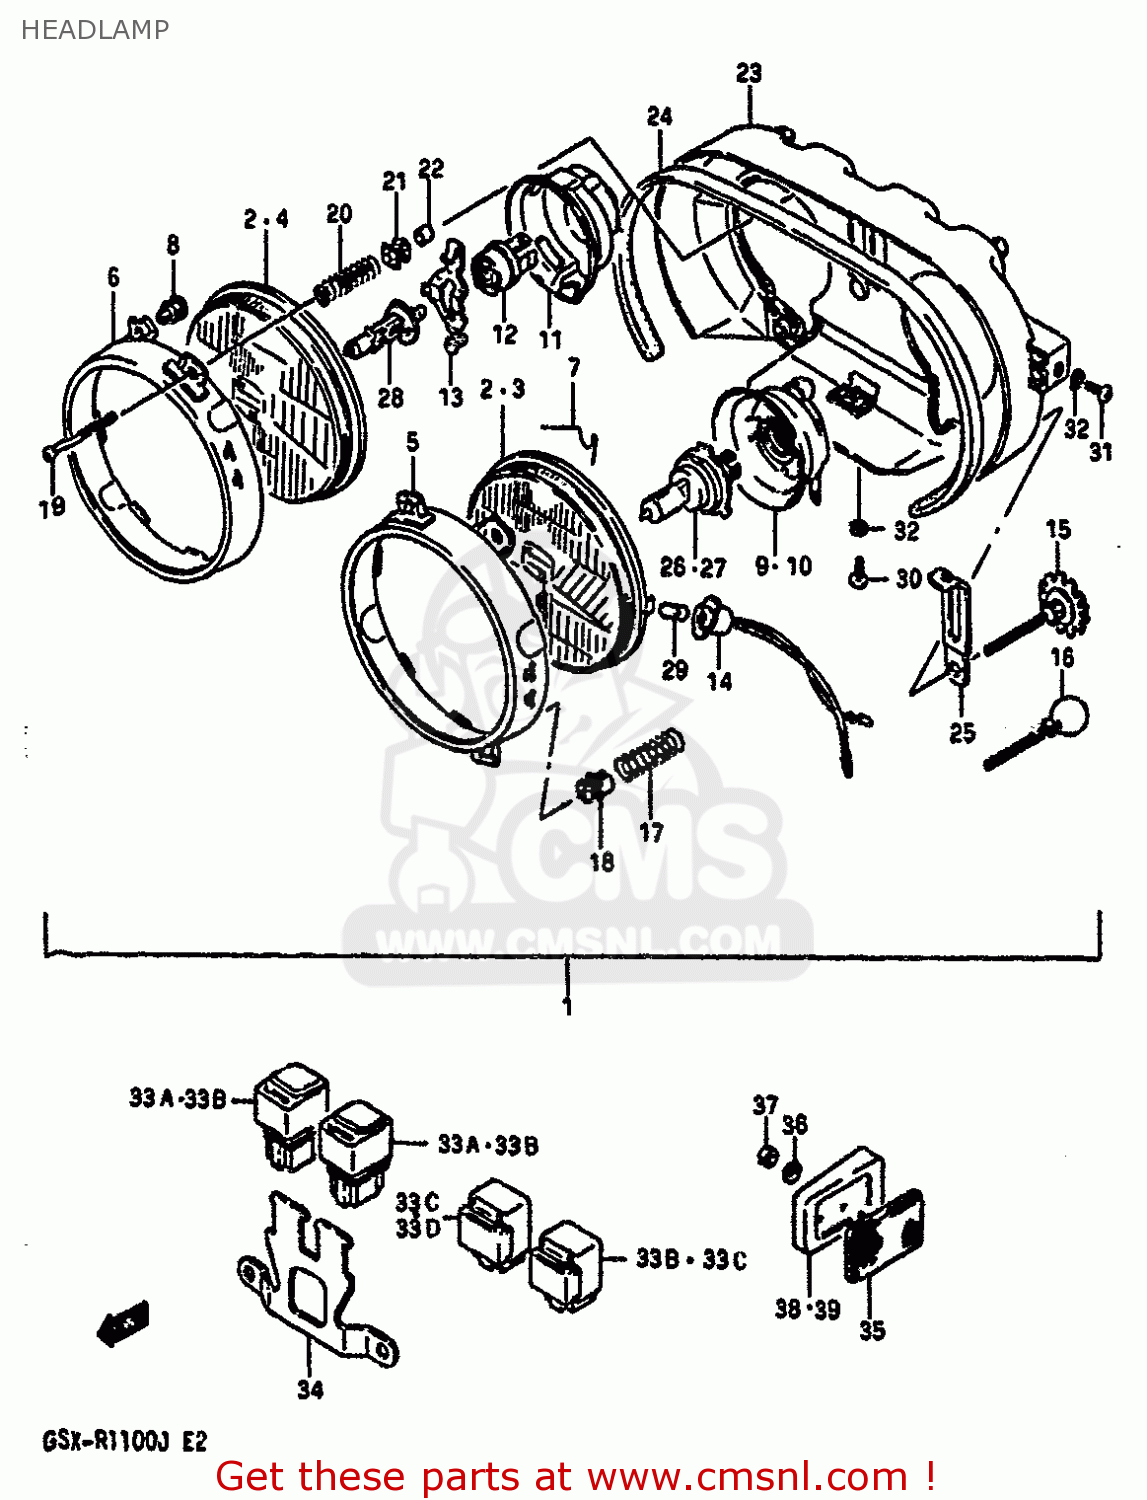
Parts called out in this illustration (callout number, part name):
1	HEADLAMP ASSY
2	UNIT
3	LAMP UNIT,L
4	UNIT,RH
5	RING,RETAINING,LEFT
6	RING,RETAINING,RIGHT
7	SPRING
8	SCREW,SPHERICAL
9	COVER,SOCKET
10	COVER,SOCKET
11	COVER, SOCKET,LH
12	ADAPTER
13	SPRING,PLATE
14	SOCKET
15	SCREW,ADJUSTER
16	SCREW,ADJUSTER
17	SPRING
18	NUT
19	SCREW,ADJUSTER
20	SPRING
21	NUT
22	CAP,SCREW
23	HOUSING,HEADLAMP
24	GASKET (NAS)
25	CLAMP
26	BULB(12V60/55W,H4)
27	BULB(12V60/55W,H4)
28	BULB(12V55W/H1/P14.5S/OSRA,PHI
29	BULB(12V4W)
30	SCREW
31	SCREW
32	WASHER,LOCK
33A	RELAY, ANTINOSE DIVE FORK
33B	RELAY, ANTINOSE DIVE FORK
33C	RELAY ASSY,HEADLAMP
33D	RELAY ASSY,HEADLAMP
34	BRACKET,HEADLAMP RELAY
35	REFLEX REFLECTOR, FRONT SIDE
36	WASHER,5MM
37	NUT
38	SPACER,FRONT SIDE,REAR,RIGHT
39	SPACER,FRONT SIDE,REAR,LEFT
